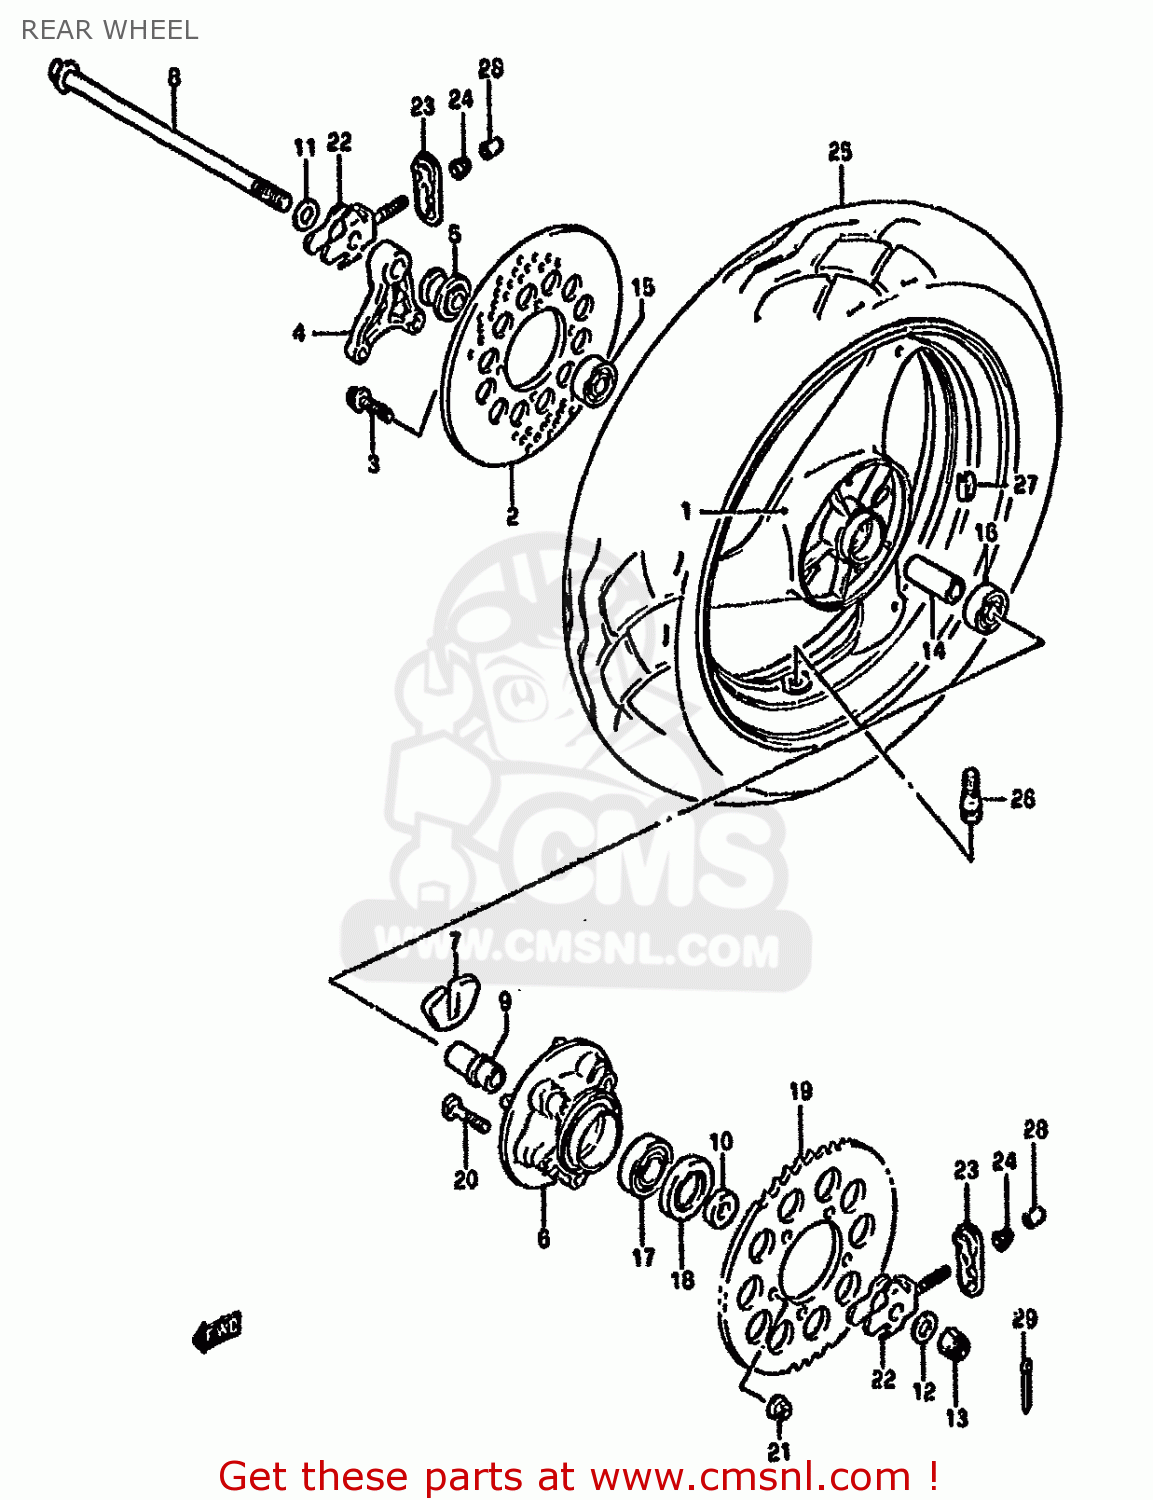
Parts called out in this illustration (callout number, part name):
1	WHEEL,REAR
2	DISC,RR BRAKE
3	BOLT
4	BRACKET,RR,CALIPER
5	SPACER,RR AXLE,R
6	DRUM,RR SPROCKET MOUNTING
7	ABSORBER,RR HUB SHOCK
8	AXLE,RR
9	RETAINER,RR SPROCKET DRUM
10	SPACER,RR AXLE,L
11	WASHER
12	WASHER(17X34X3)
13	NUT
14	SPACER(17.5X25X78)
15	BEARING
16	BEARING
17	BEARING(25X62X17)
18	SEAL,OIL(35X62X8)
19	SPROCKET,REAR
20	BOLT
21	NUT
22	ADJUSTER,CHAIN
23	PLATE,CHAIN ADJUSTER
24	NUT
25	TIRE,RR(150/70-17 69H)
26	VALVE ASSY,WHEEL RIM(TR412)
27	BALANCER,WHEEL
28	CAP,CHAIN ADJUSTER
29	PIN,COTTER
